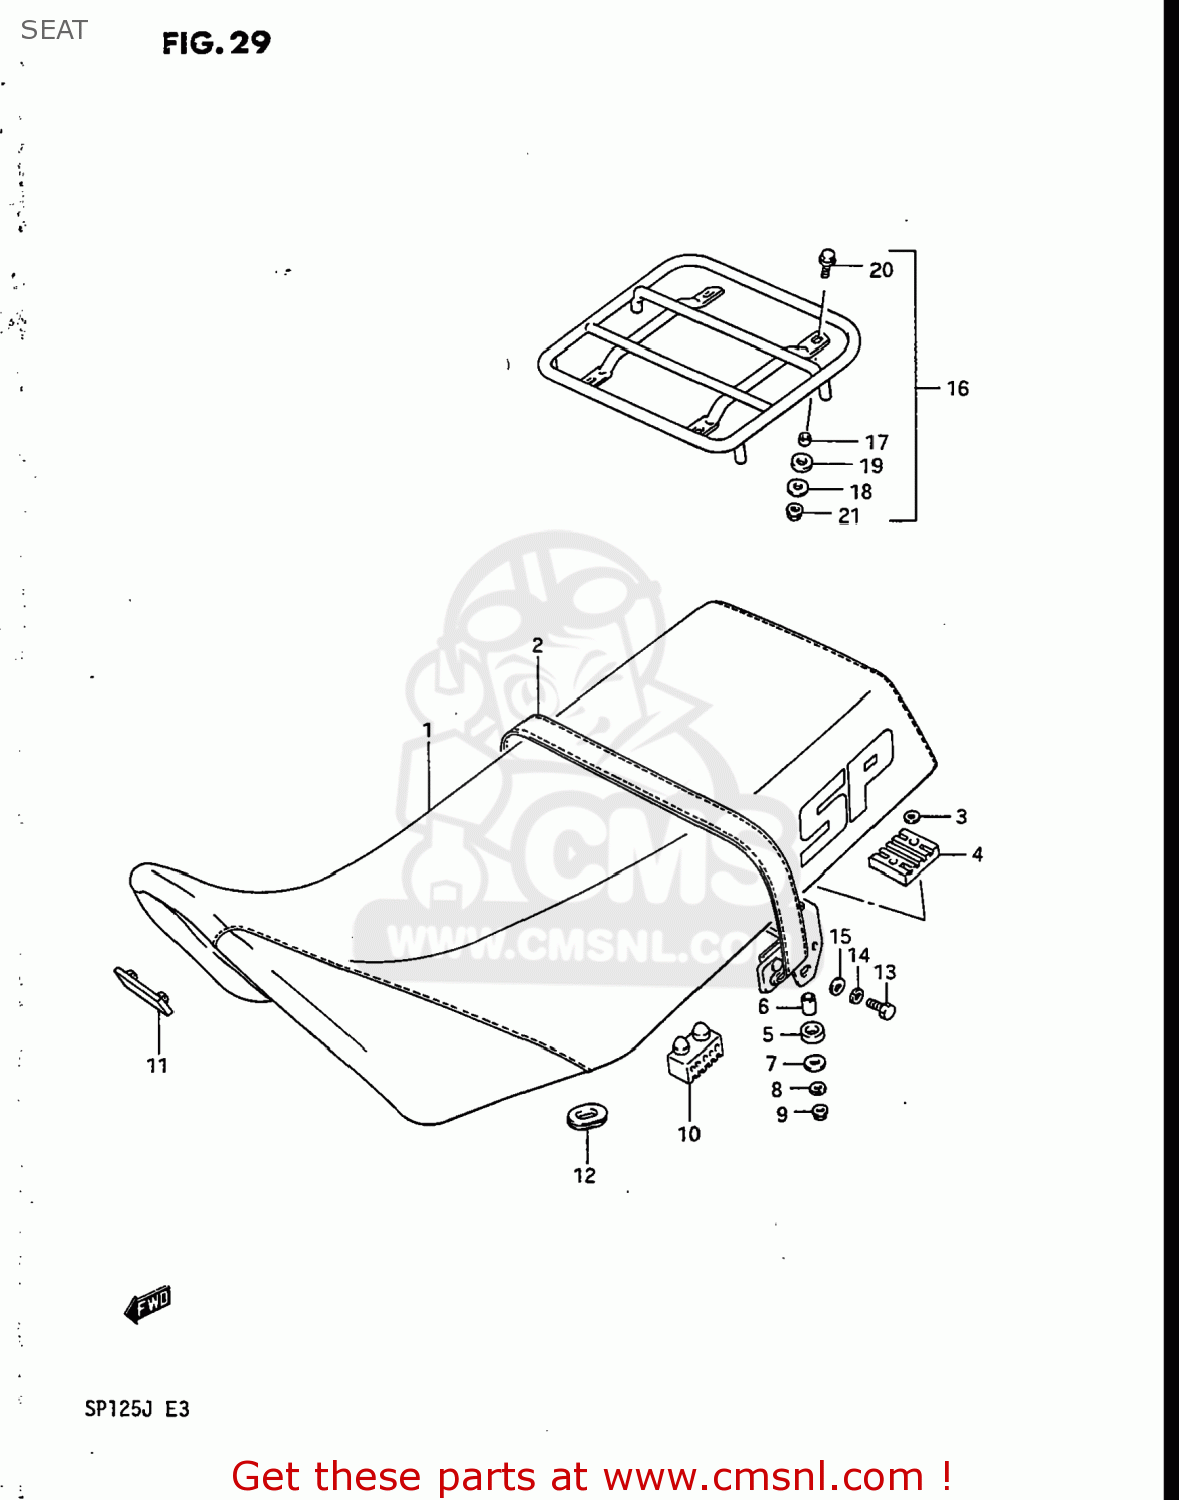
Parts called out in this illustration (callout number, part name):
1	SEAT ASSEMBLY
2	BAND,SEAT
3	WASHER, LOWER
4	CUSHION,FR PLATE
5	CUSHION,SEAT FR
6	SPACER,SEAT SUPPORT
7	WASHER
8	WASHER,LOCK
9	NUT
10	CUSHION,SEAT(40X20X15)
11	CUSHION
12	CUSHION
13	BOLT
14	WASHER,LOCK,8.
15	WASHER
16	CARRIER SET,SUPPORT
17	SPACER
18	WASHER(6.5X18X1)
19	CUSHION
20	BOLT
21	NUT 6MM
